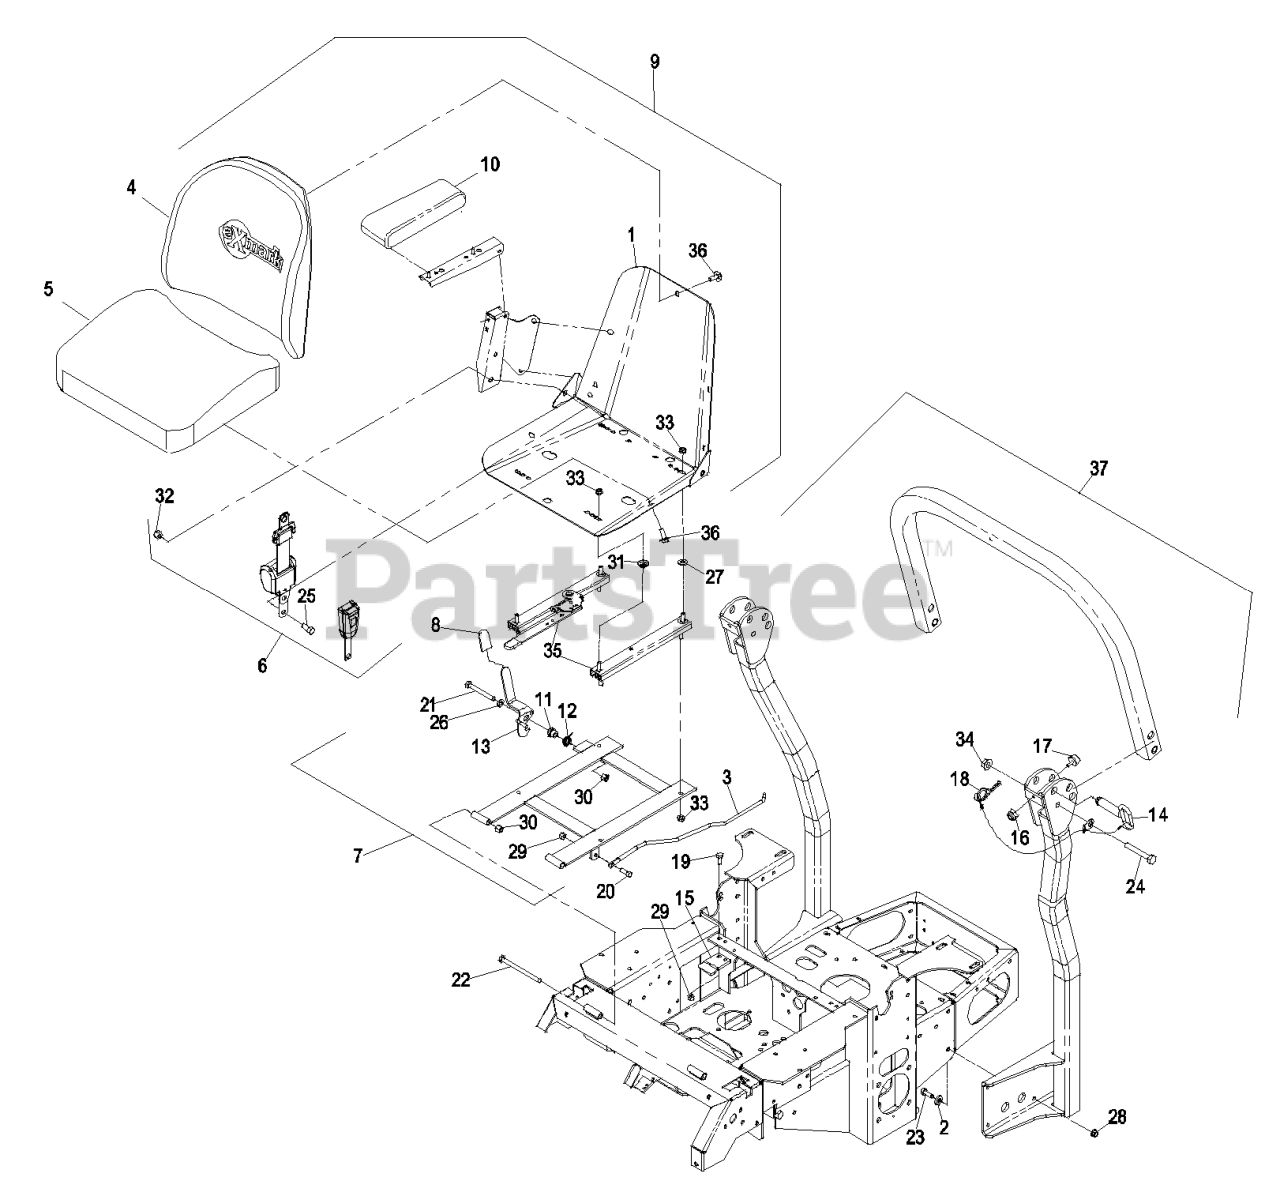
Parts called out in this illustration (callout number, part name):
1	FRAME-SEAT
2	WASHER-BELLEVILLE
3	ROD-RETAINER, SEAT
4	CUSHION,SEAT BACK
5	CUSHION,SEAT BOTTOM
6	RETRACTABLE SEATBELT KIT
7	ASM,SEAT FRAME
8	GRIP-LEVER
9	KIT,SEAT W/ARMREST ADJ.
10	CUSHION,ARMREST RH
11	BUSHING-LATCH, SEAT
12	SPRING-TORSION
13	LATCH ASM
14	PIN-FOLD, ROPS
15	CATCH-LATCH, SEAT
16	NUT-LOCK, NI
17	BUMPER-RUBBER
18	HAIRPIN
19	SCREW-HH
20	SCREW-HH
21	SCREW-HH
22	SCREW-HH
23	SCREW-HH
24	SCREW-HH
25	SCREW-HH
26	WASHER-FLAT
27	WASHER-FLAT
28	NUT-HHF, WHIZ
29	NUT-LOCK, NI
30	NUT-LOCK, NI
31	SPACER-TRACK
32	NUT-LOCK
35	TRACK-SEAT
36	BOLT-SEAT
37	Frpsl Kit, Rops Lhp
